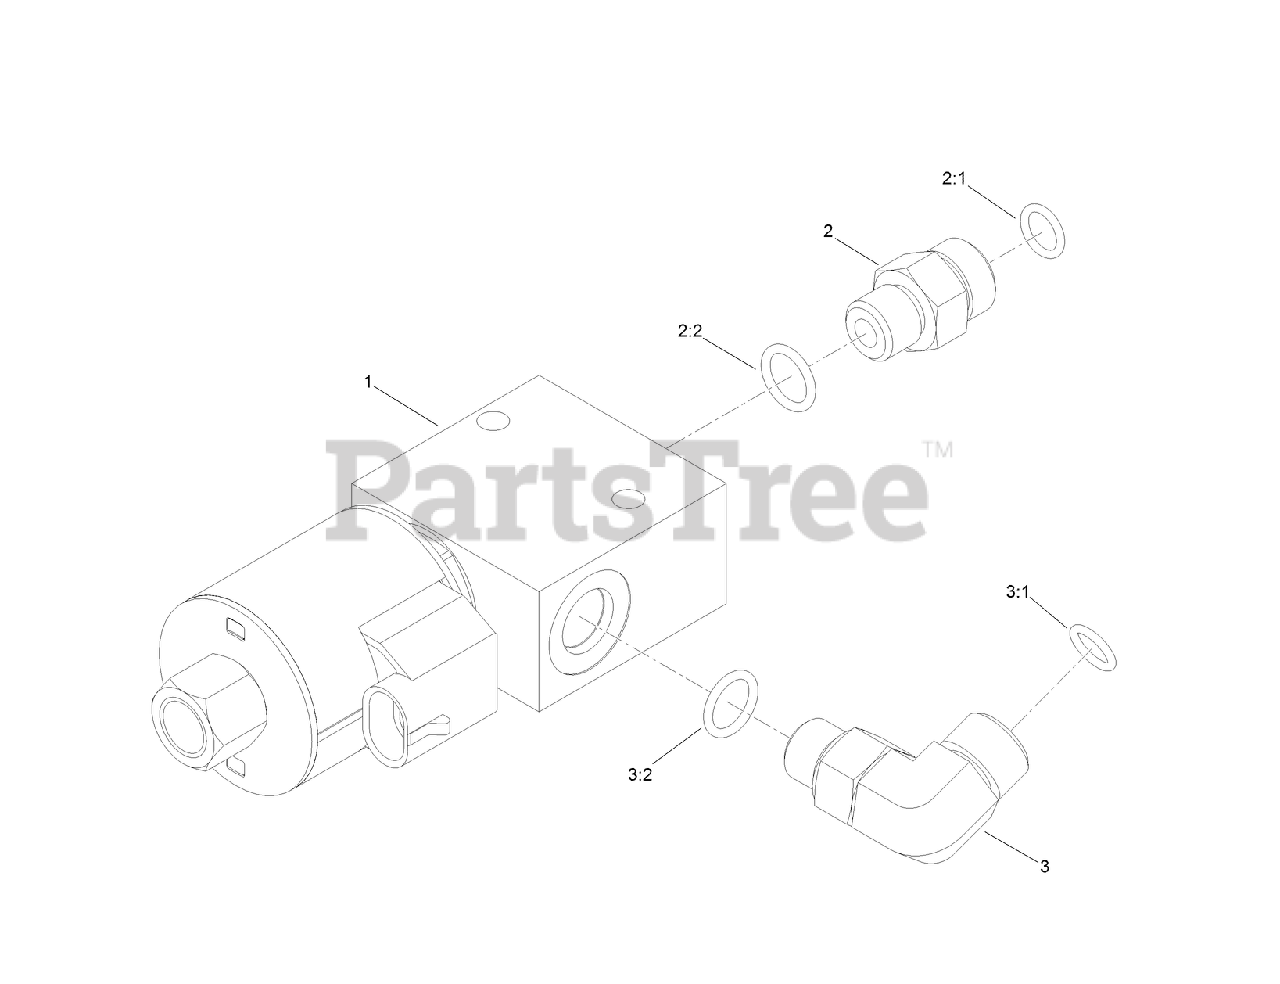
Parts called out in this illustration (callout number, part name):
1	MANIFOLD-RELIEF, PROPORTIONAL
2	FITTING-STRAIGHT
2:1	O-RING
2:2	O-RING
3	FITTING-ELBOW, 90 DEG
3:1	O-RING
3:2	O-RING
